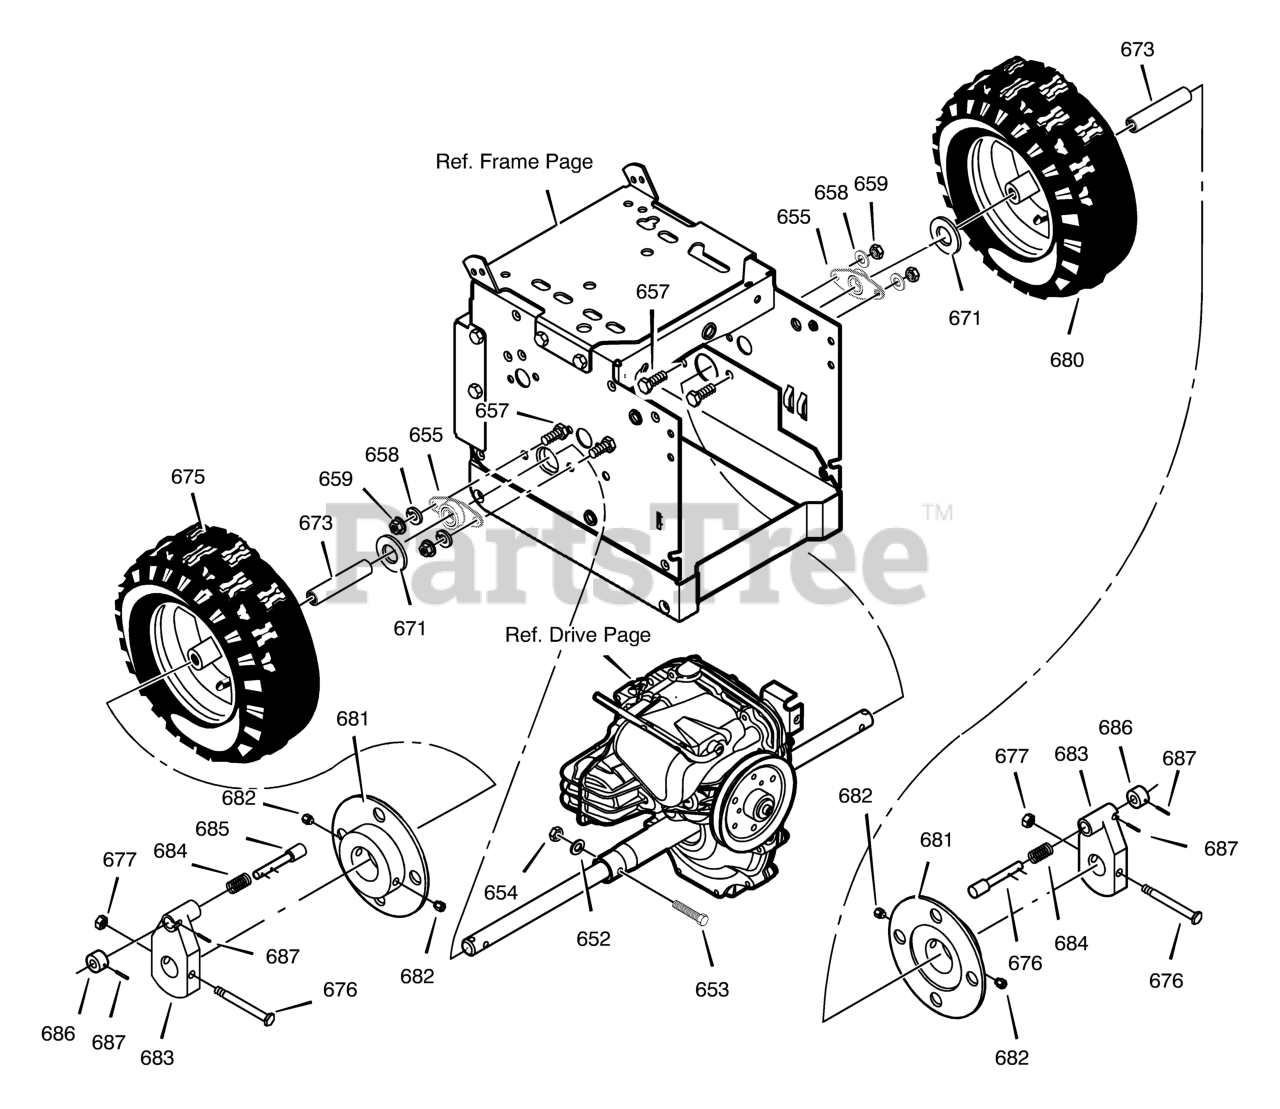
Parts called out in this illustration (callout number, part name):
653	SCREW, 1/4-20X1.75
654	NUT, 1/4-20
655	BEARING & RETAINER ASSY
657	SCREW, 3/8-16 x .75
658	WASHER, SPLTLK
659	NUT, 3/8-163
671	WASHER, FLAT
673	BUSHING, WHEEL
675	TIRE & RIM, RIGHT
676	SCREW, 1/4-20 X 2.25
677	NUT, 1/4-20
680	TIRE & RIM, LEFT
681	DISC, WHEEL
683	HUB, WHEEL LOCK
684	SPRING
685	PIN, LOCK
686	KNOB
687	PIN
